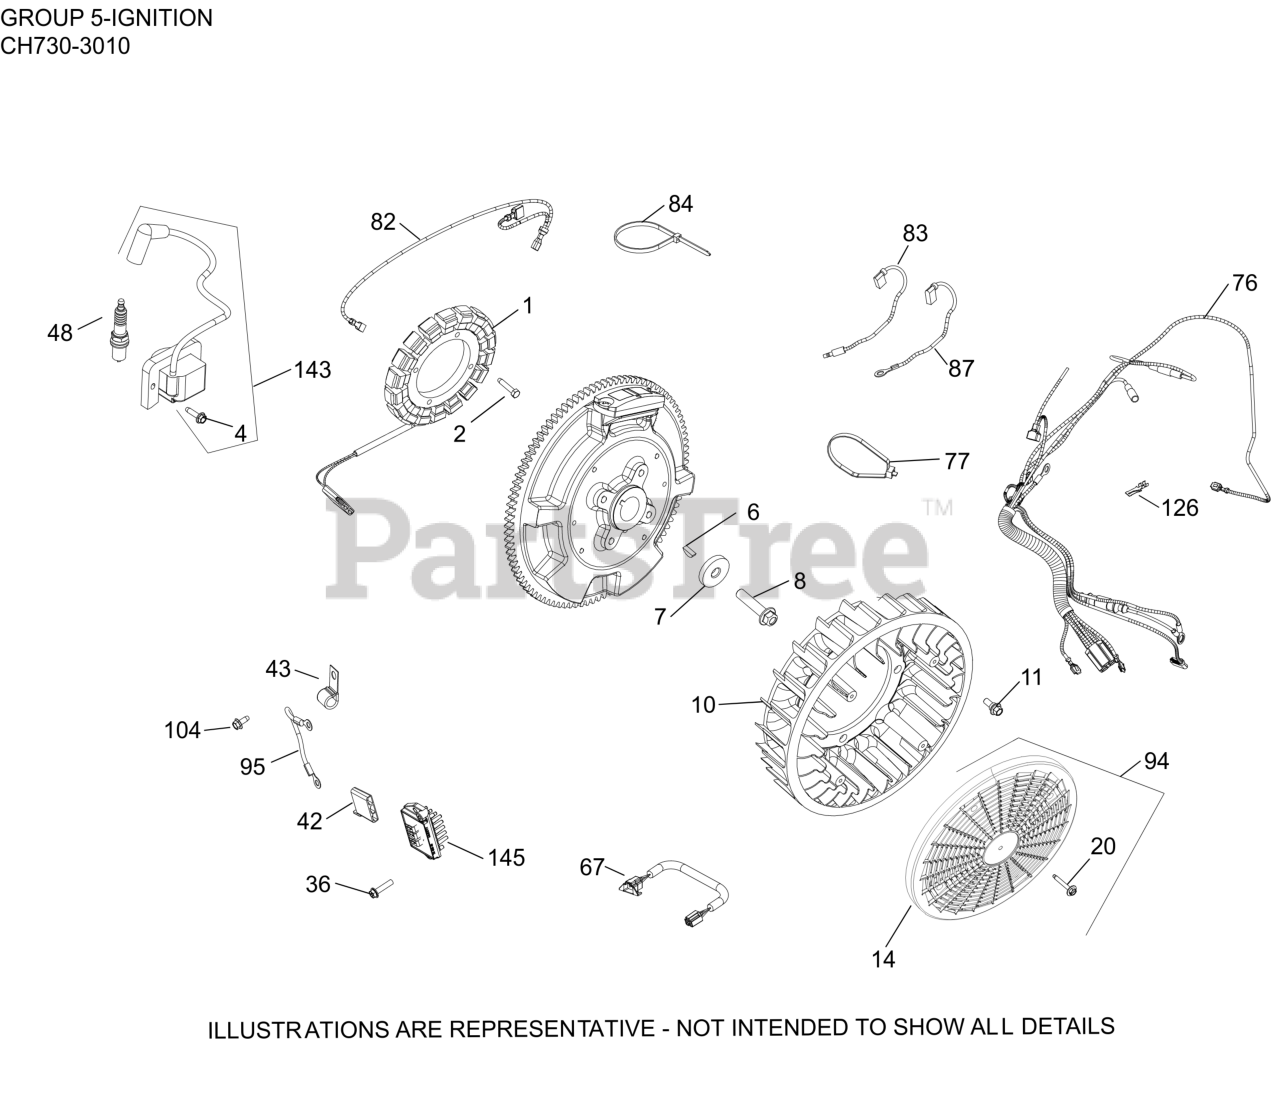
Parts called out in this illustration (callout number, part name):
1	KIT, 15 / 20 AMP STATOR
2	SCREW, THREAD FORMING
4	SCREW, THREAD FORMING
6	KEY, 3/16" X 5/8"
7	WASHER, FLAT
8	SCREW, HEX FLANGE
10	FAN-USE 24 755 253-S
11	BOLT, SHOULDER
14	SCREEN, GRASS
20	SCREW, FLG SEMS M4x.7x25
36	SCREW, HEX FLANGE HI-LO
42	CONNECTOR
43	CLIP, CABLE
48	PLUG, SPARK (PRO SERIES)
67	CONNECTOR
76	HARNESS WIRING ASSEMBLY
82	LEAD, DUPLEX
83	LEAD, OIL SENTRY
87	LEAD, 20/25 AMP B+
94	KIT GRASS SCREEN
104	SCREW, THREAD FORMING
143	KIT IGNITION MODULE
145	REGULATOR, RECTIFIER (20-30AMP,FW W/OVP)
NI	FLYWHEEL ASSEMBLY (CV/CH670 & 730)
